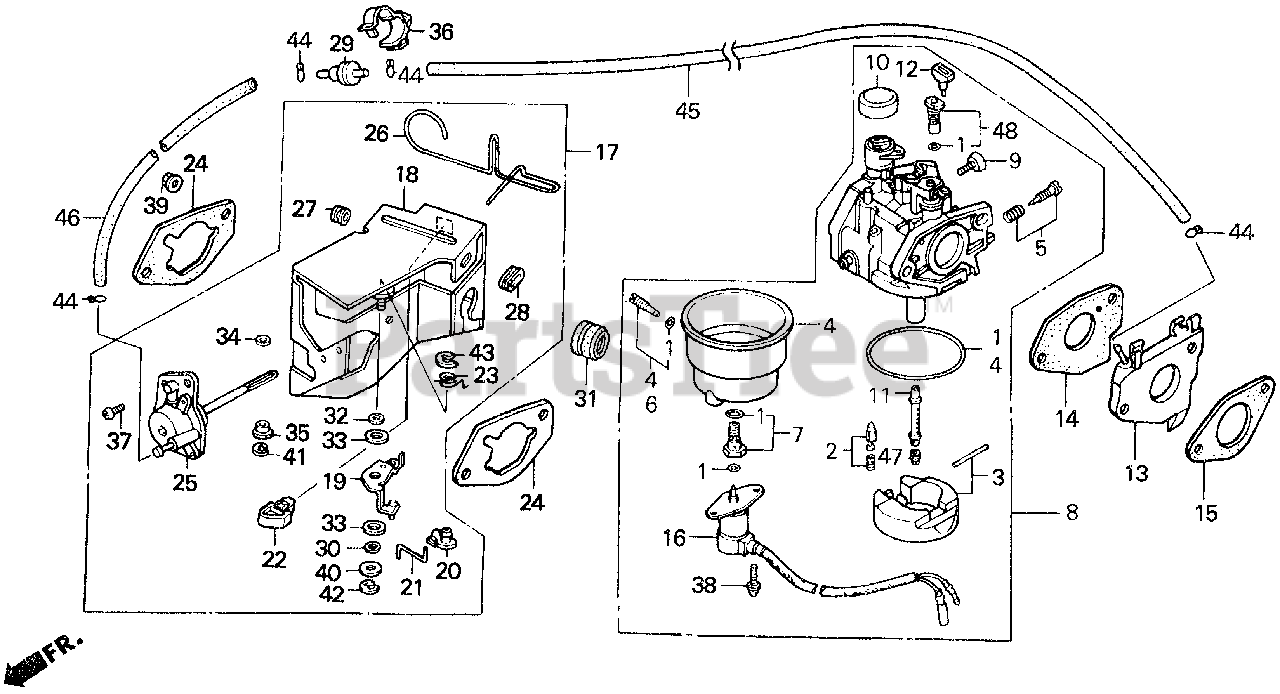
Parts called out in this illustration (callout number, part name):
1	GASKET SET
2	VALVE SET, FLOAT
3	FLOAT SET
4	CHAMBER SET, FLOAT
5	SCREW SET
6	SCREW SET, DRAIN
7	SCREW SET B
8	CARBURETOR ASSY. (BE82B B)
9	SCREW, THROTTLE STOP
10	CAP, CHOKE LEVER DUST
11	NOZZLE, MAIN
12	COLLAR, SET
13	INSULATOR, CARBURETOR
14	GASKET, CARBURETOR
15	GASKET, INSULATOR
16	VALVE ASSY., SOLENOID
17	STAY ASSY., MANUAL CHOKE
18	STAY, SOLENOID
19	LEVER, CHOKE
20	JOINT, ROD
21	ROD, CHOKE
22	STOPPER, CHOKE ROD
23	SPRING, MANUAL CHOKE
24	GASKET, AIR CLEANER
25	DIAPHRAGM ASSY.
26	ROD, CHOKE CONTROL
27	GROMMET, CHOKE ROD
28	GUIDE, CHOKE ROD
29	VALVE, DASHPOT CHECK
30	BUSH, ARM PIVOT
31	GROMMET, FENDER
32	WASHER, CHOKE LEVER
33	SEAL, CHOKE LEVER
34	WASHER, THRUST (2.7X8)
35	COLLAR, LEVER
36	CLIP, WIRE HARNESS
37	SCREW, PAN (5X12)
38	SCREW-WASHER (5X12)
39	NUT, FLANGE (6MM)
40	WASHER, PLAIN (5MM)
41	E-RING (2MM)
42	E-RING (4MM)
43	E-RING (7MM)
44	CLIP, TUBE (B7)
45	BULK HOSE, VACUUM (3.5X8000) (3.5X75)
46	BULK HOSE, VACUUM (3.5X8000) (3.5X130)
47	JET, MAIN (#95)
47	JET, MAIN (#98)
47	JET, MAIN (#100)
48	JET SET, PILOT (#35)
